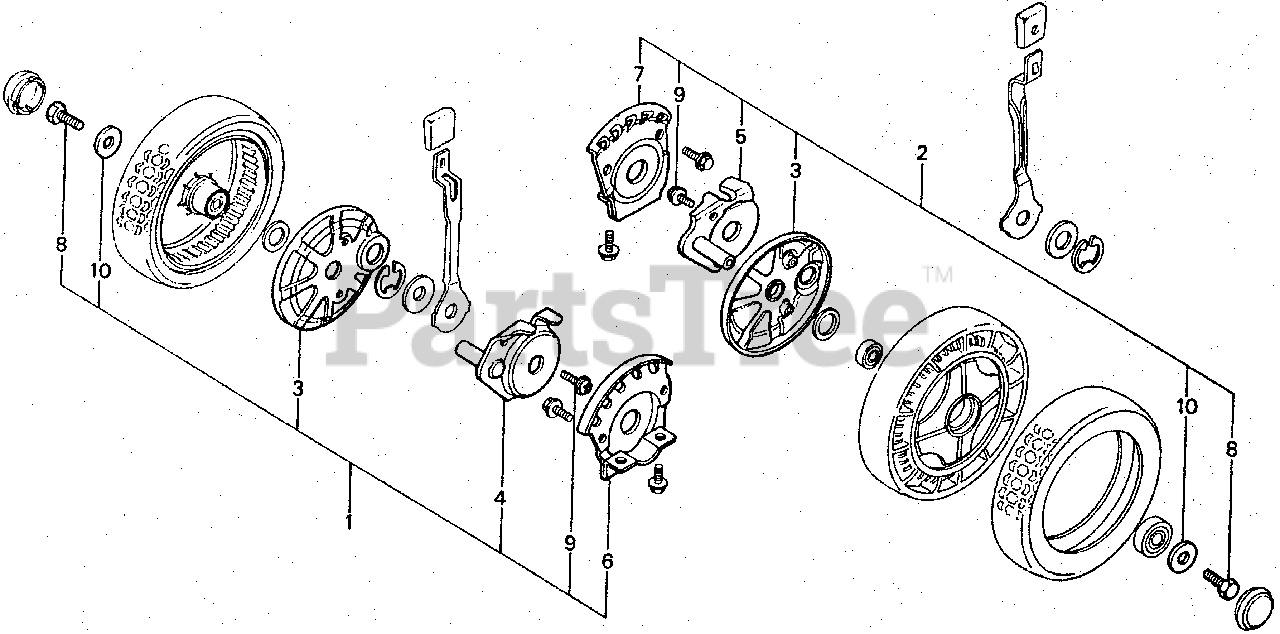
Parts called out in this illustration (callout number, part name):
1	ADJUSTER KIT, R. RR. HEIGHT
2	ADJUSTER KIT, L. RR. HEIGHT (NOT AVAILABLE)
3	COVER, WHEEL
4	ARM, R. RR. ADJUSTING
5	ARM, L. RR. ADJUSTING
6	PANEL, R. RR. ADJUSTING
7	PANEL, L. RR. ADJUSTING
8	BOLT, HEX. (8X12)
9	SCREW-WASHER (4X14)
10	WASHER, PLAIN (8MM)
